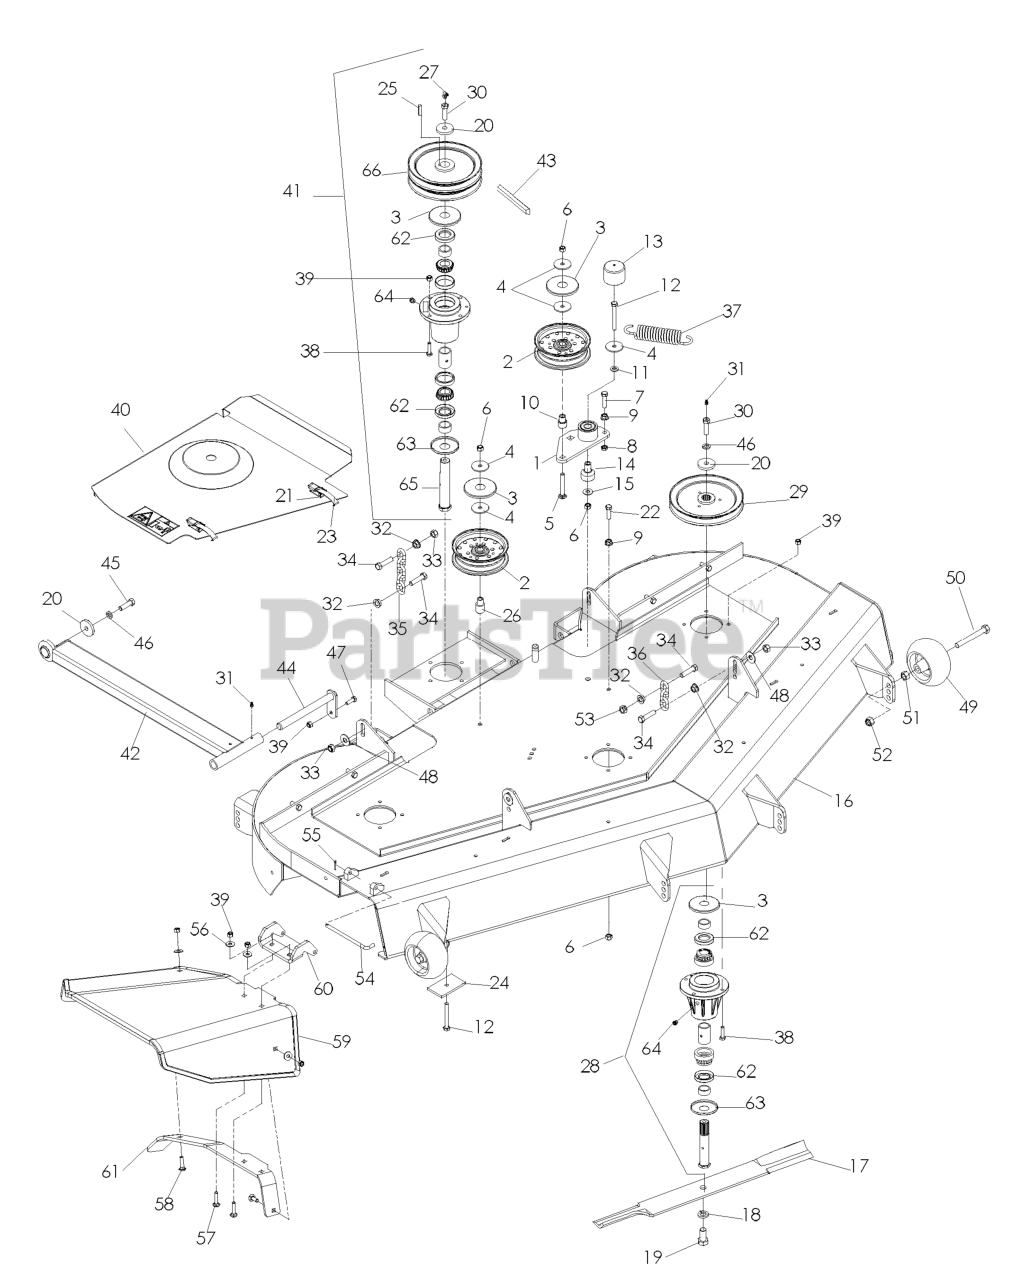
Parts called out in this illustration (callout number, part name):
1	ARM-IDLER W/BRG
2	IDLER PULLEY
3	TOP DUST CAP
4	WASHER, 3/8 SPEC
5	RHSNB 3/8-16 X 2.75
6	NUT 3/8-16 NYLOC
7	HCS 3/8-16 X 1-1/2
8	NUT 3/8-16 HEX JAM
9	NUT 3/8C WHIZ
10	BUSHING, IDLER
11	WASHER 3/8 SAE FLAT
12	HCS 3/8C X 3
13	CAP, VINYL
14	PIVOT, BEARING
15	WASHER 3/8 FLAT
16	DECK W/DECALS
17	BLADE OEM - 25"
18	LOCKWASHER 5/8
19	HCS 5/8F X 1 1/4
20	SPINDLE WASHER
21	RIVET, BLIND, 5/32 DIA
22	HCS 3/8C X 1 1/4 GR5
23	DRAW LATCH
24	SUPPORT PLATE
25	KEY 1/4 SQ X 1 1/8
26	IDLER BUSHING
28	HOUSING ASM, 52/61
29	PULLEY, 72
30	HCS 7/16-20 GD 8 SPEC
31	ZERK
32	NUT 7/16C WHIZ
33	7/16-14 HEX NUT W/NYL RING ZD
34	HCS 7/16 - 14 X 1 3/4
35	LIFT CHAIN
36	LIFT CHAIN - 3 LINK
38	HCS 5/16C X 1 1/4
39	NUT 5/16 NYLOC
40	72 BELT SHIELD ASM - RH
40	72 BELT SHIELD ASM LH
41	BAM L44 JACKSHAFT ASM LOWER
42	STRUT WELDMENT
43	BELT, DECK
44	PIN WELDMENT
45	HCS 7/16F X 1 1/2
46	WASHER 7/16 LOCK
47	HCS 5/16C X 1
48	WASHER 7/16 FLAT ZD
49	GAUGE WHEEL
50	HHB, 1/2-13X4
51	NUT HEX 1/2
52	NUT 1/2-13 HEX NYLOC ZD
53	NUT 7/16C CENTERLOCK
54	PIN, CHUTE PIVOT
55	RP_COTTER PIN 1/8 X 3/4
56	WASHER 5/16 FLAT
57	RHSNB 5/16-18 X 1-1/2 GR 5 ZD
58	BOLT, CARRIAGE 5/16X1-1/4
59	CHUTE, RUBBER DISCHARGE 72"
60	PIVOT BRACKET - RUBBER CHUTE
61	BRACKET REINF, CHUTE
62	SHAFT SEAL
63	BOTTOM DUST CAP
64	PLUG-VENTED
65	JACKSHAFT SPINDLE
66	SHEAVE WSL
